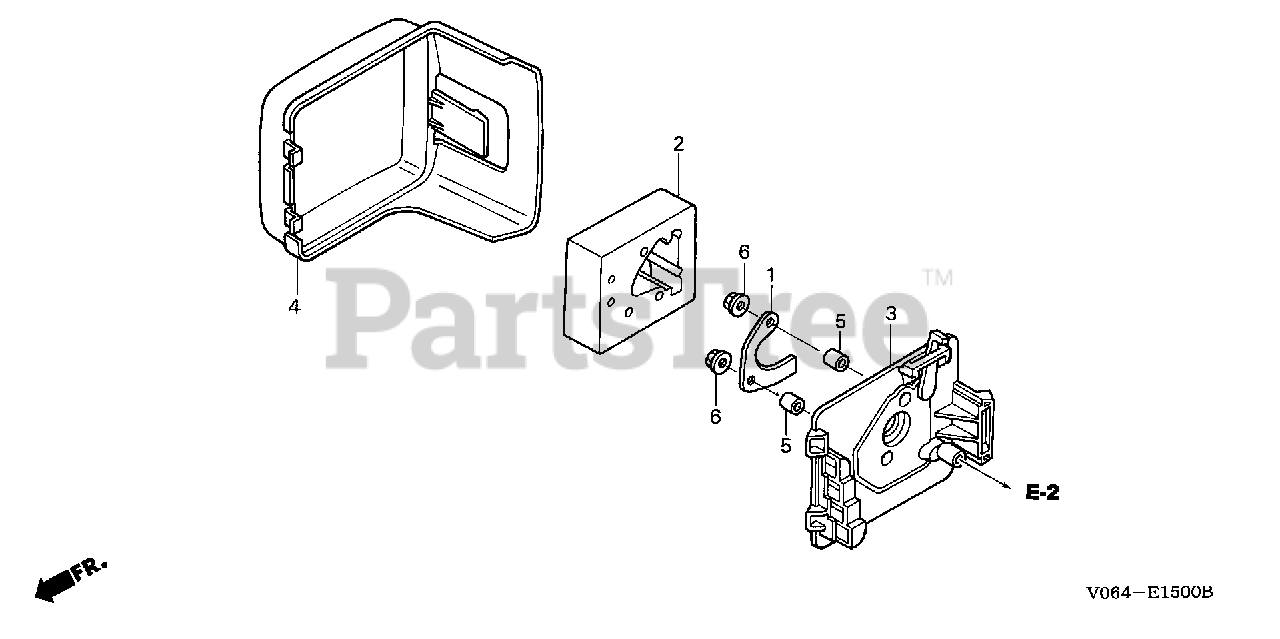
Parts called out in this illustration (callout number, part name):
1	PLATE, OIL TRAP
2	ELEMENT, AIR CLEANER (SEMI-DRY)
3	HOUSING, AIR CLEANER *R291R* (DARK POWER RED)
4	COVER, AIR CLEANER *R280* (POWER RED)
5	COLLAR, AIR CLEANER
6	NUT, FLANGE (5MM)
